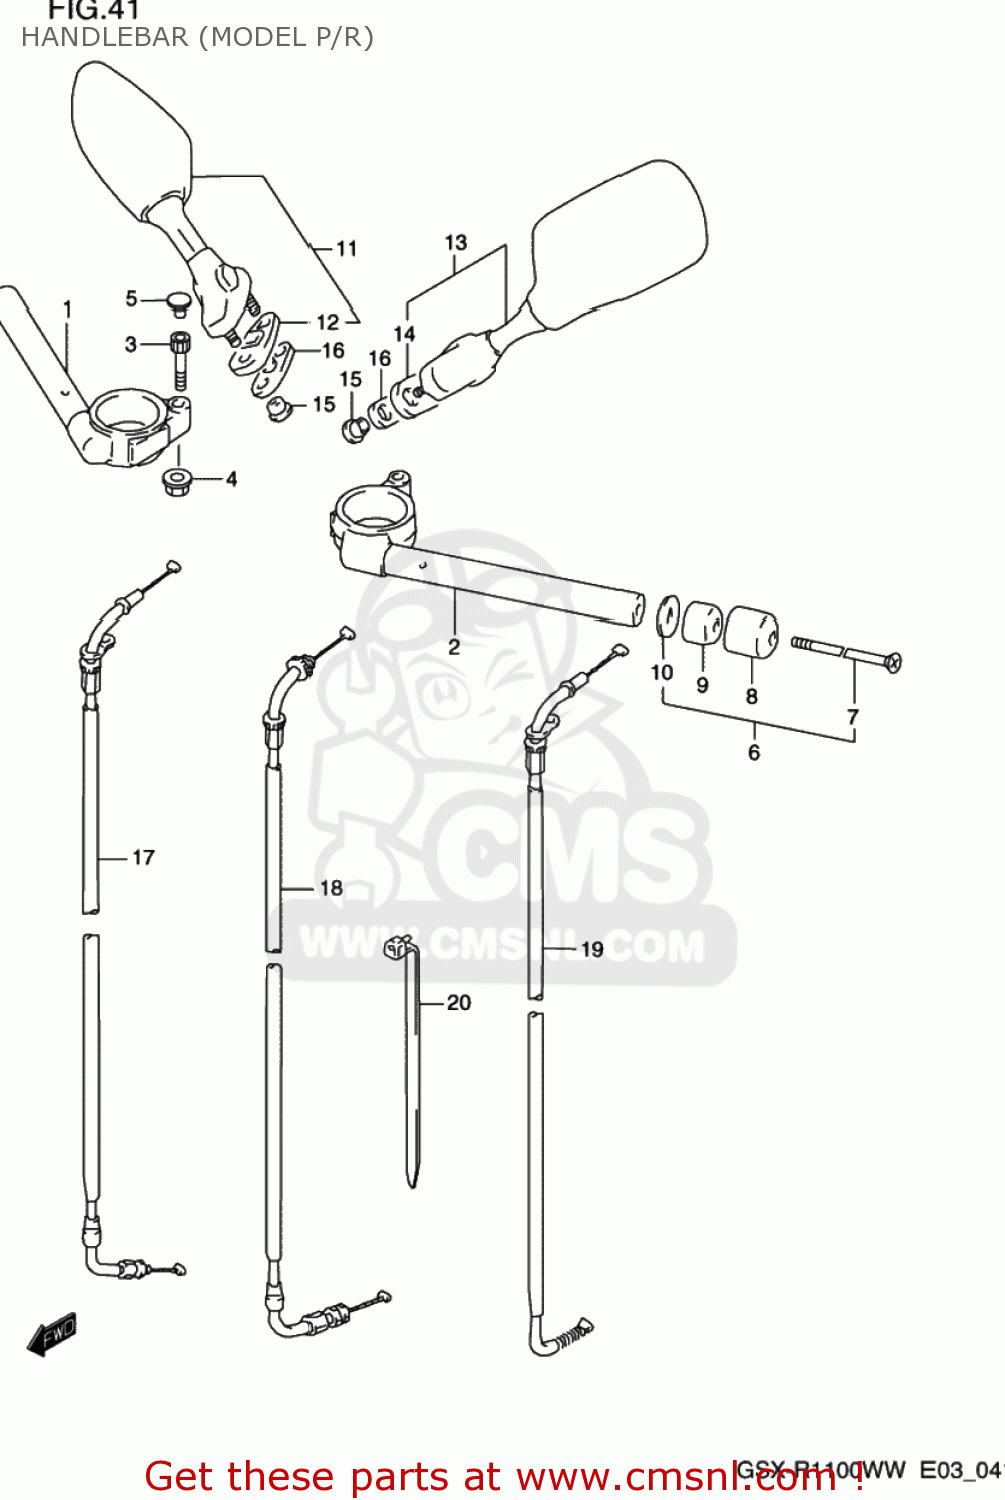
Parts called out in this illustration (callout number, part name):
1	HANDLEBAR,RIGHT
2	HANDLEBAR,LEFT
3	BOLT
4	NUT
5	CAP(OD:12)
6	BALANCER SET,HANDLEBAR
7	SCREW
8	CAP,BALANCER
9	BALANCER,HANDLEBAR
10	SPACER,BALANCER
11	MIRROR ASSY,RR VIEW,R
12	GASKET,RR VIEW MIRROR,R (NAS)
13	MIRROR ASSY,RR VIEW,L
14	GASKET,RR VIEW MIRROR,L (NAS)
15	NUT,RR VIEW MIRROR
16	CUSHION,RR VIEW MIRRORR
17	CABLE ASSY,THROTTLE NO.1
18	CABLE ASSY,THROTTLE NO.2
19	CABLE,STARTER
20	CLAMP(L:235)
